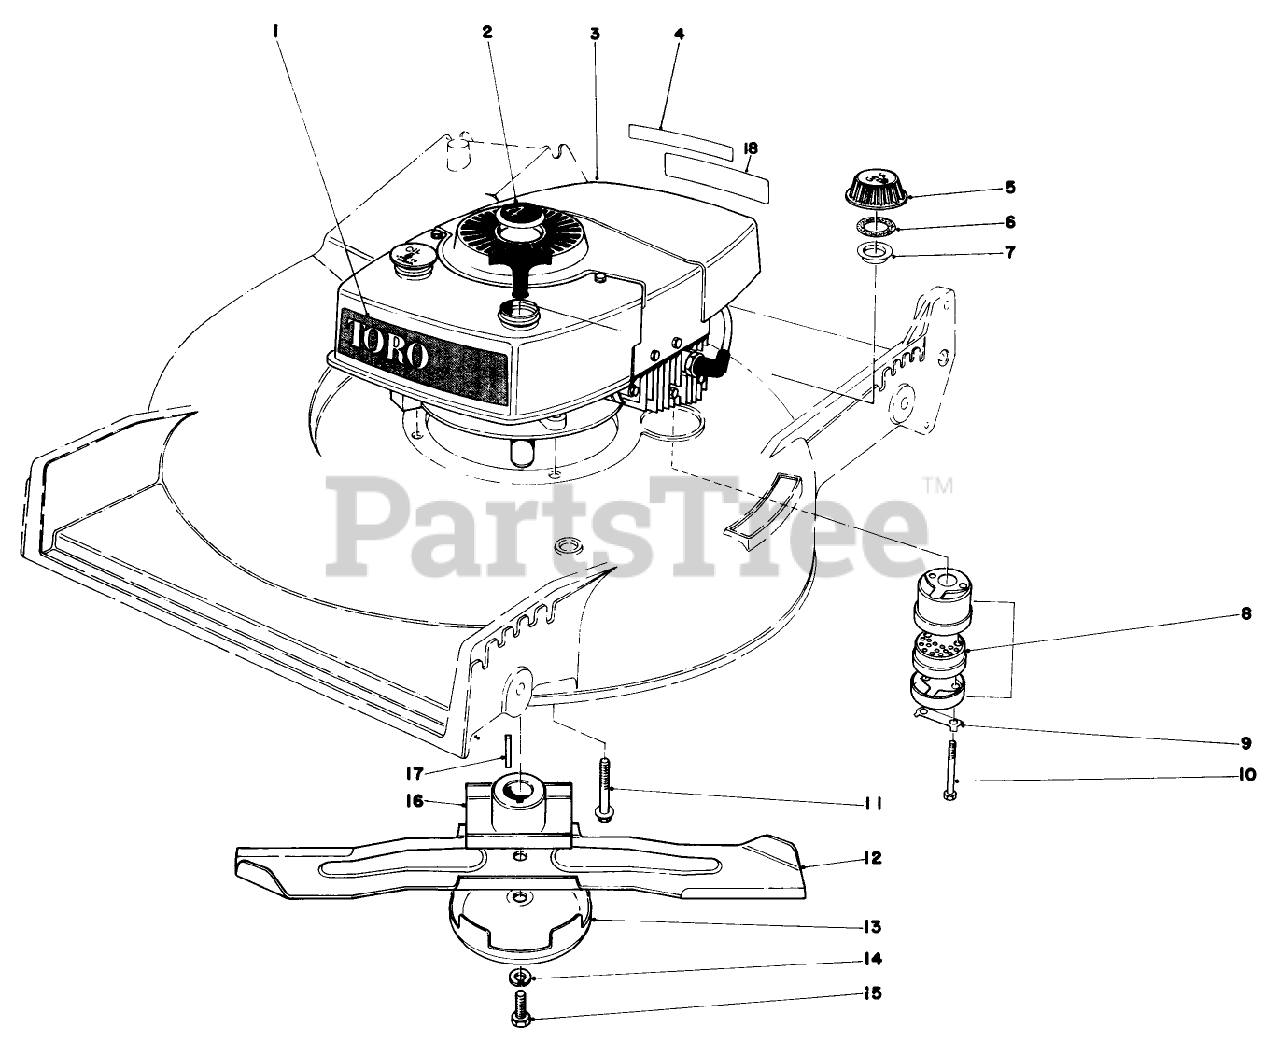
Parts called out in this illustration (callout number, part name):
1	Decal Toro
2	Plug Button
3	Engine
4	Snap Ring
5	Gas Cap (Incl. Ref. #6 & 7)
6	GASKET
7	GAS CAP BAFFLE
8	Muffler Assembly (Incl. Ref. #9 & 10)
9	CLIP - LOCKING
10	SCREW-HH
11	SCREW-HWHTF
12	Blade
13	AntiScalp Cup
14	WASHER-LOCK
15	BLADE SCREW
16	BLADE RETAINER WA(BLACK)
17	KEY-SQUARE
18	Decal Maintenance
